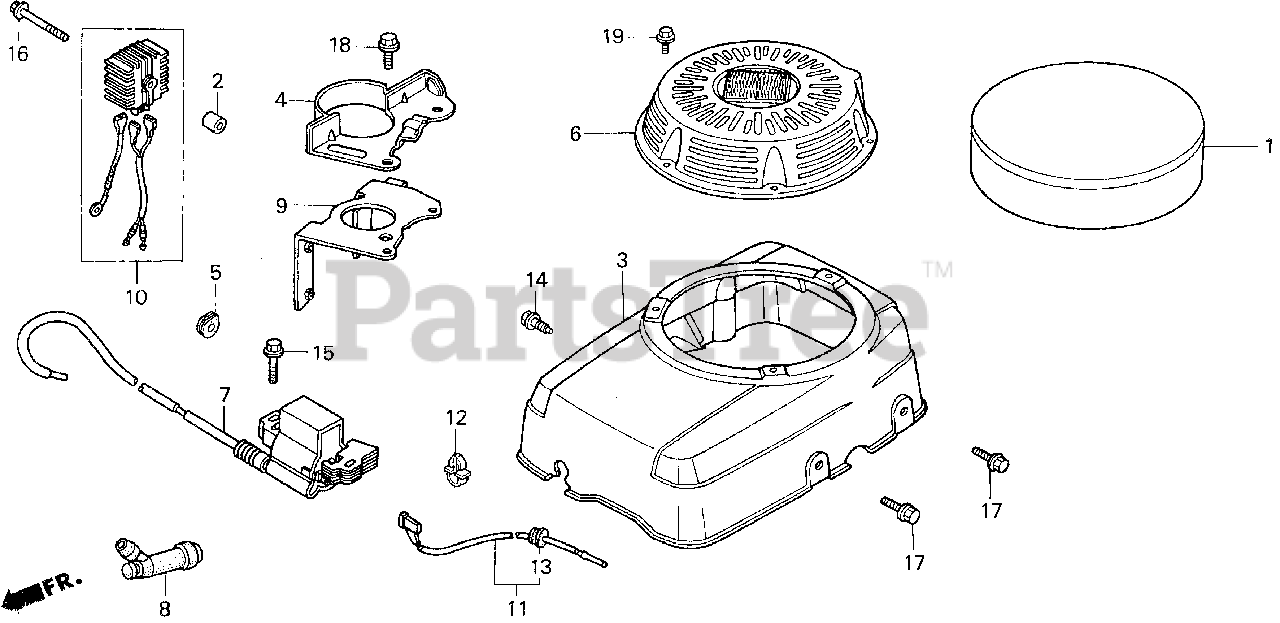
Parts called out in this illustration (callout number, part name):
1	FILTER COMP., AIR
2	SPACER, AIR CLEANER ELBOW
3	COVER COMP., FAN *R8* (BRIGHT RED)
4	PLATE COMP., SIDE
5	GROMMET, WIRE
6	HOOD COMP., FAN COVER
7	COIL ASSY., IGNITION
8	CAP ASSY., NOISE SUPPRESSOR
9	STAY COMP., STARTER
10	RECTIFIER ASSY., SILICON
11	WIRE, STOP SWITCH
12	HOLDER, STOP SWITCH WIRE
13	GROMMET, WIRE
14	BOLT, FLANGE (6X12) (CT200)
15	BOLT, FLANGE (6X28)
16	BOLT, FLANGE (6X40)
17	BOLT, FLANGE (8X16)
18	BOLT, FLANGE (8X28)
19	BOLT, FLANGE (6X12)
